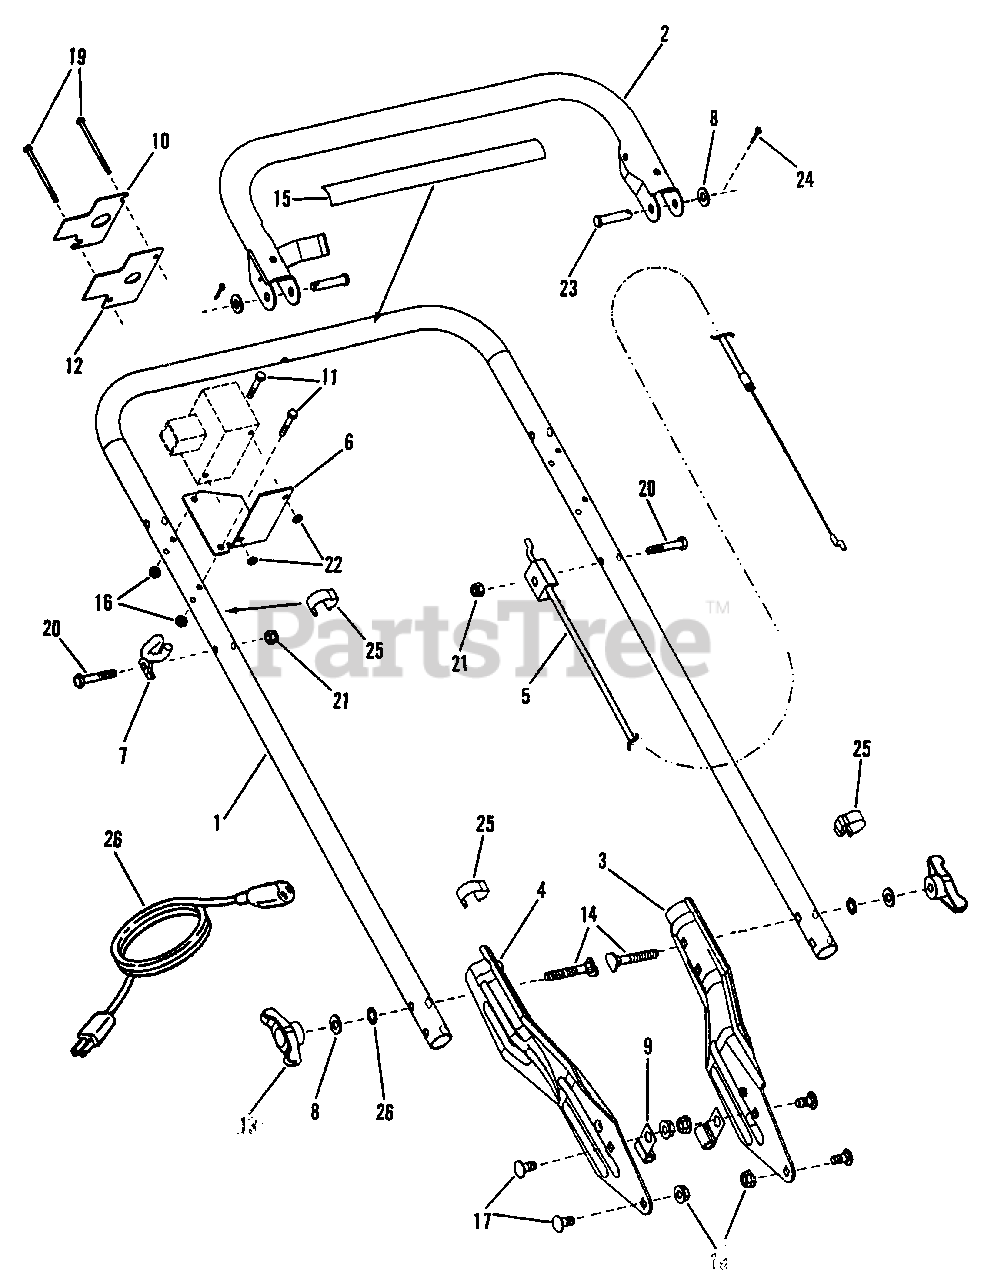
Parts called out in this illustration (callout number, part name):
1	HANDLE, Upper
2	WELDMENT, Bail (OPC)
3	HANDLE, Lower (Left Hand)
4	HANDLE, Lower (Right Hand)
5	CONTROL, Blade
6	BRACKET, Electric Starter
7	GUIDE, Pull Rope
8	WASHER, 5/16" Flat
9	CLIP, 7/16" Wiring Harness
10	DECAL, Starting Button ES
11	BOLT, #10-24 x 1-1/4" Hex Head, Grade 5
12	COVER, Electric Start
13	KNOB, 5/16-18 Wing (Black)
14	SCREW, 5/16-18 x 2" Curved Head, Grade 2
15	DECAL, Starting Procedure ES
16	NUT, #10-24 Hex Keps Lock
17	BOLT, 5/16-18 x 5/8" Short Neck Carriage, Grade 5
18	NUT, 5/16-18 Hex Flange Lock, Grade 5
19	SCREW, 06-32 x 2-1/2" Hex Head Cap
20	SCREW, 1/4-20 x 1-1/2" Hex Head Cap, Grade 5
21	NUT, 1/4-20 Hex Nyloc
22	NUT, #6-32 Hex Keps Lock
23	PIN, 5/16 x 1.42" Clevis
24	PIN, 3/32 x 1-1/2" Cotter
25	CLIP, Wiring Harness
26	CORD, 10 Ft. Extension
27	WASHER, 5/16" Internal Tooth Lock
